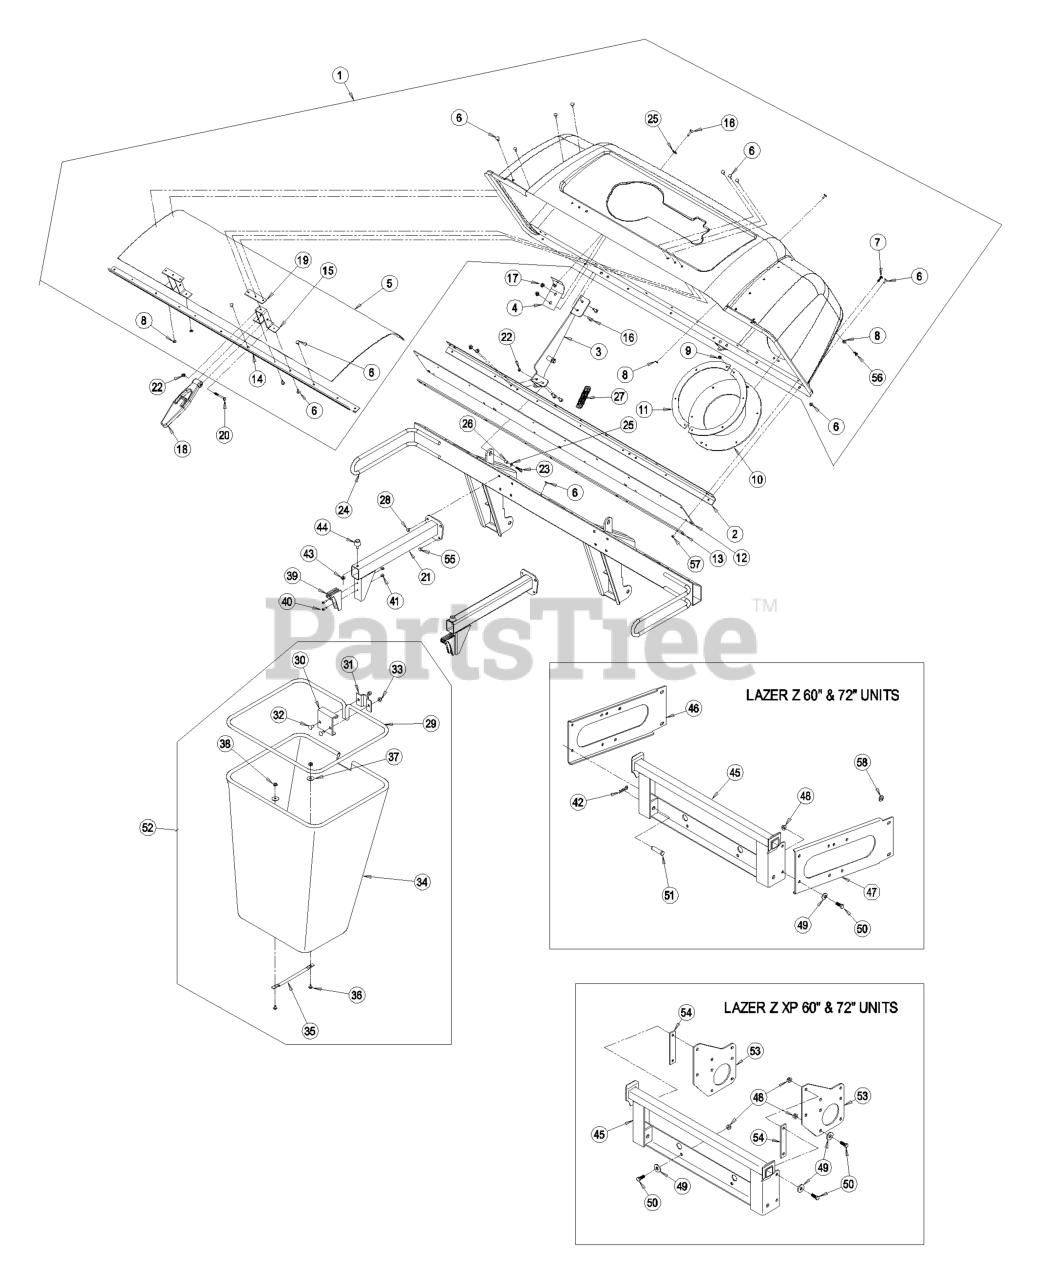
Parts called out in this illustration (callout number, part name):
1	ASM, HOOD
2	STIFFENER-BAGGER, TOP
3	HINGE ASM
4	REINFORCEMENT-HOOD, BAGGE
5	SCREEN-BAGGER
6	RIVET-BLIND
7	SCREW-HEAD, TRUSS
8	WASHER-FLAT
9	NUT-LOCK, NI
10	SEAL-TUBE
11	CLAMP-SEAL
12	SEAL-HINGE
13	PLATE-BACKING
14	SUPPORT-SCREEN
15	BRACKET-MOUNT
16	SCREW-HH
19	PLATE-LATCH, REINFORCEMEN
20	SCREW-HH
21	SUPPORT-BAG
22	NUT-LOCK, NI
23	SCREW-HH
24	UPRIGHT BAGGER ASM
25	WASHER-FLAT
27	SPRING-EXTENSION
28	SCREW-HH
29	FRAME-BAG
30	HANGER-BAG
32	BOLT-CARR
33	NUT-LOCK, NI
35	HANDLE-BAG
36	BOLT-CARR
38	NUT-LOCK, NI
40	SCREW-PPH
42	PIN-COTTER
45	MOUNT-BAGGER
46	BRACKET-FRAME, LH
47	BRACKET-FRAME, RH
48	NUT-HHF, WHIZ
49	WASHER-BELLEVILLE
50	SCREW-HH
51	PIN-CLEVIS
53	PLATE-MOUNT, BAGGER
55	SCREW-HSBH
56	SCREW-PPH
57	NUT-LOCK, SIDE
